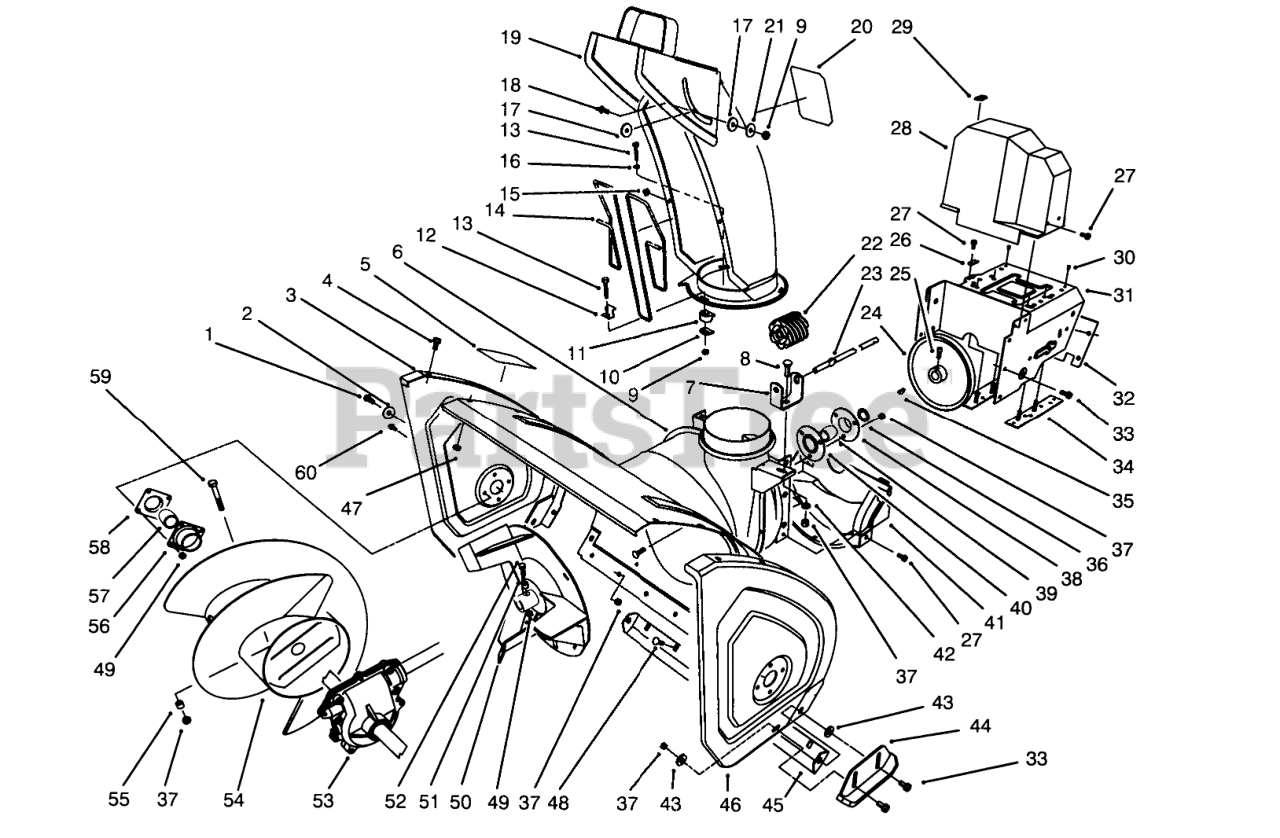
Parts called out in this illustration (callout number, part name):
1	SCREW-HH
2	WASHER
3	Plate-Side
4	SCREW-HHF
5	DECAL-WARNING, AUGER
6	Housing-24 Inch
7	BRACKET-WORM, CHUTE
8	BOLT-CARR
9	NUT-LOCK, NI
10	PLATE-RETAINER, CHUTE
11	RETAINER-CHUTE
12	CLIP-GUARD, CHUTE
13	SCREW-HSH
14	GUARD-CHUTE
15	NUT-PUSH
16	WASHER-FLAT
17	WASHER-PLASTIC
19	Assembly
20	Decal-Danger
21	WASHER-FLAT
22	GEAR-WORM
23	ROD-CHUTE, LOWER
24	PULLEY-IMPELLER
25	SCREW-SET, SQH
26	RETAINER-CABLE
27	SCREW-HWH
28	COVER-BELT, UPPER
29	COVER-CABLE
30	RIVET-POP
31	Frame-Engine
32	Cover-Frame, Engine
33	SCREW-HHF
34	LH FRAME PLATE ASM
35	KEY-WOODRUFF
36	WASHER-THRUST
37	NUT-LOCK, NI
38	Flange-Bearing (Front)
39	BEARING-BALL
40	Flange-Bearing ((Rear)
41	COVER-BELT, LOWER
42	WASHER-PLAIN
43	WASHER
44	Skid
45	Blade-Scraper
46	Plate-Side
47	NUT-LOCK, NI
48	SCREW-CARR
49	NUT-LOCK, NI
50	Impeller
51	SPACER
52	SCREW-HHF
53	AUGER GEARCASE ASM
54	Auger-RH
55	SPACER-HUB, AUGER
56	BEARING-FLANGE, FRONT
57	BEARING
58	BEARING-FLANGE, REAR
59	SCREW-HH
60	SCREW-HH
